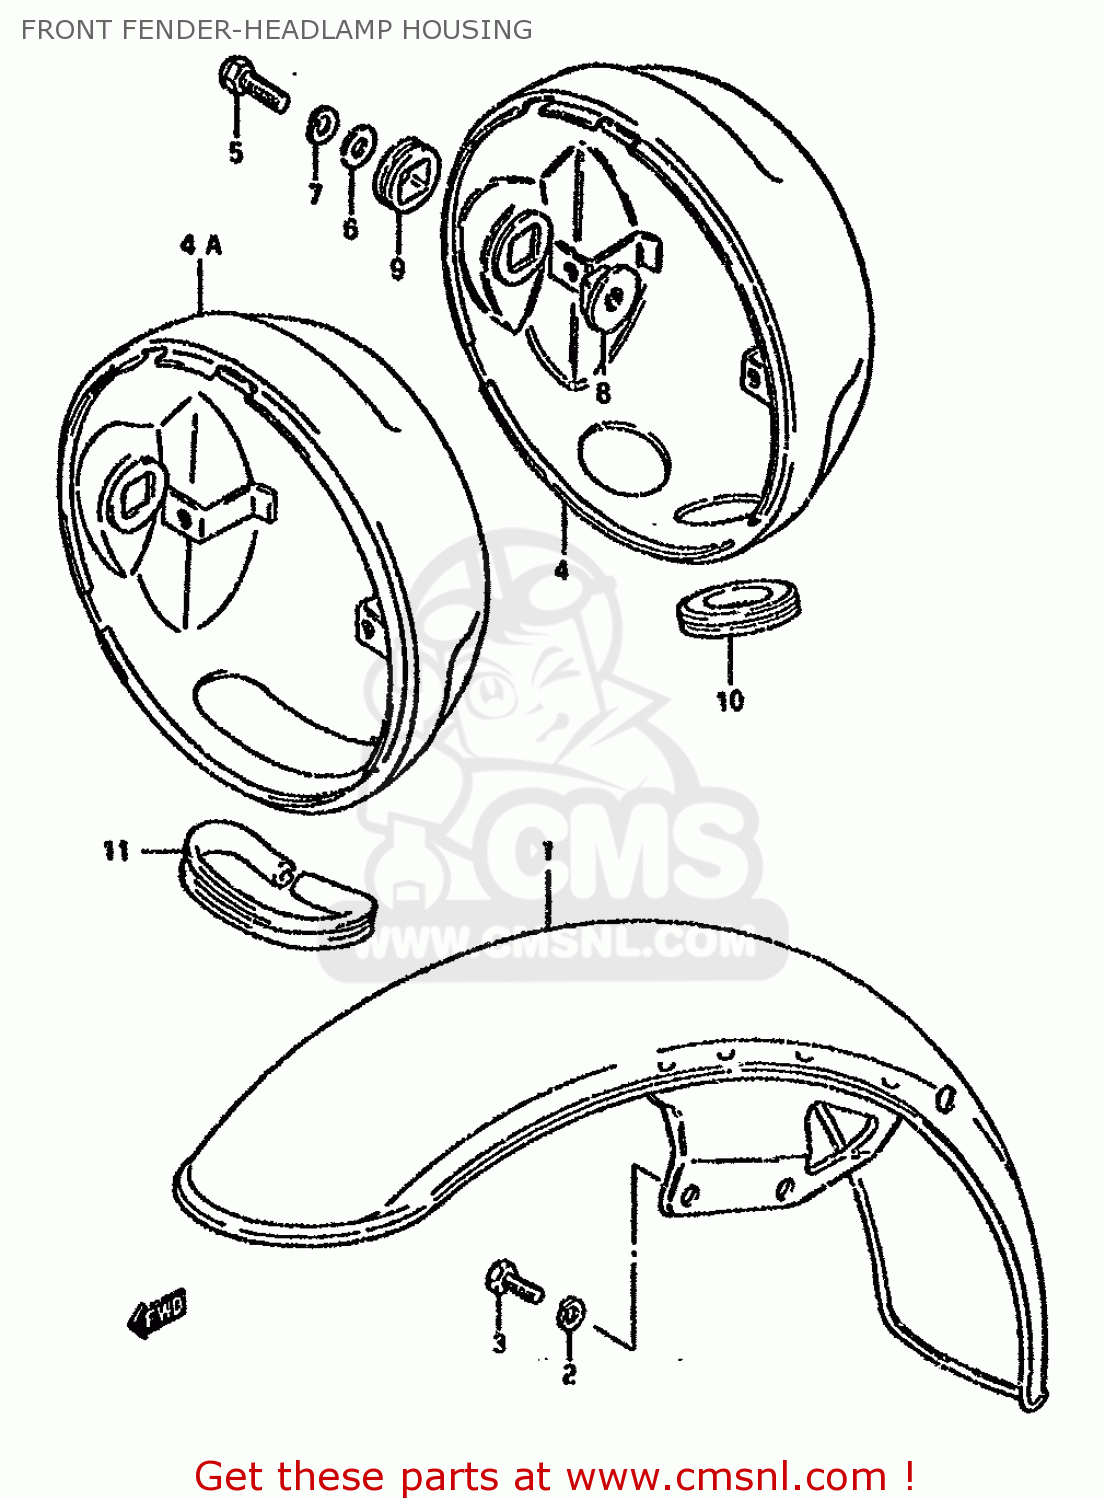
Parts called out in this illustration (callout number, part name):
1	FENDER,FR
2	LOCK WASHER
3	BOLT
4	HOUSING,HEADLAMP
4A	HOUSING,HEADLAMP
5	BOLT
6	WASHER
7	LOCK WASHER
8	SPACER,HEADLAMP HOUSING
9	CUSHION,HEADLAMP HOUSING
10	GROMMET,HEADLAMP HOUSING
11	MOLDING WINDSCREEN
